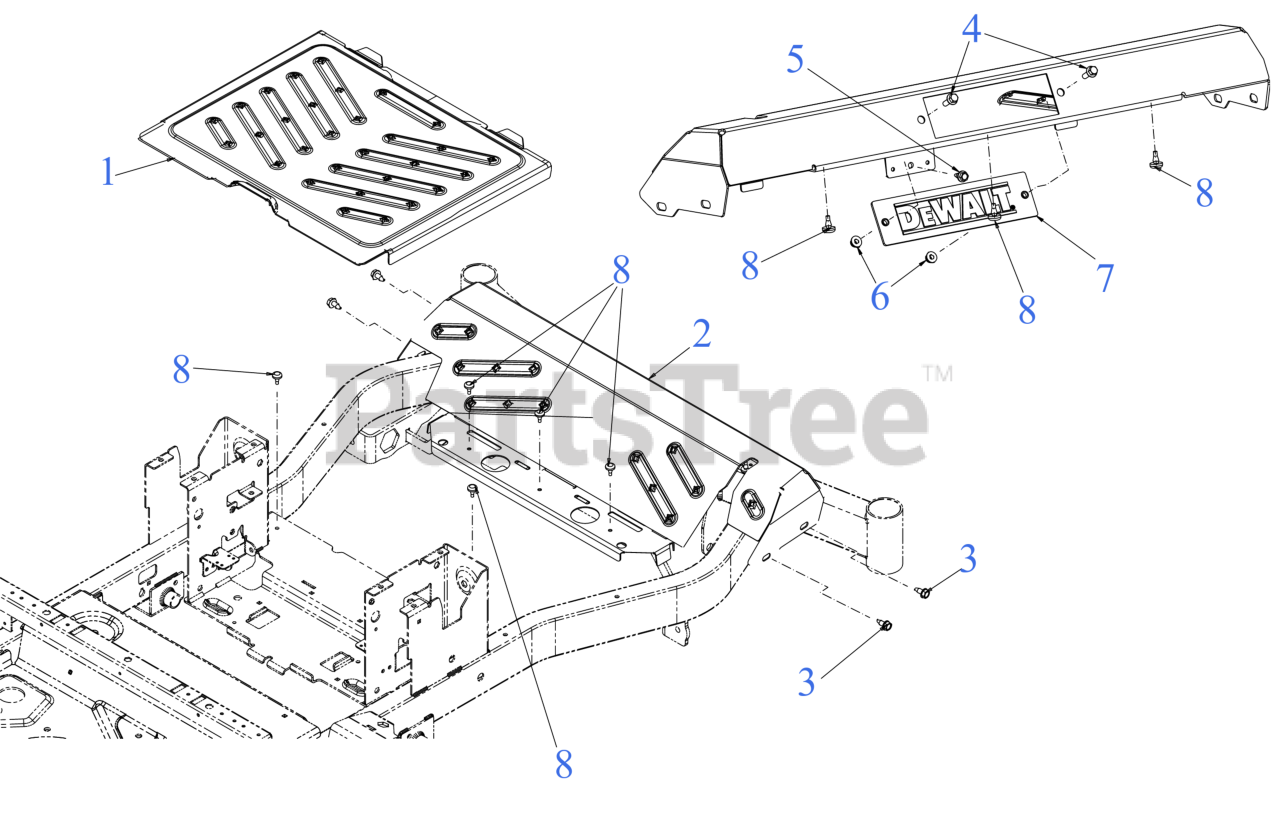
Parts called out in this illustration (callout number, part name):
1	FLOORBOARD
2	FOOTREST BRACKET
3	SCREW 5/16-18 x .750
4	SCREW 1/4-20 x .75 GR5
5	SCREW 1/4-20X.625
6	FLANGE LOCK NUT
7	DEWALT LOGO (DIE CAST)
8	RUBBER BUMPER
